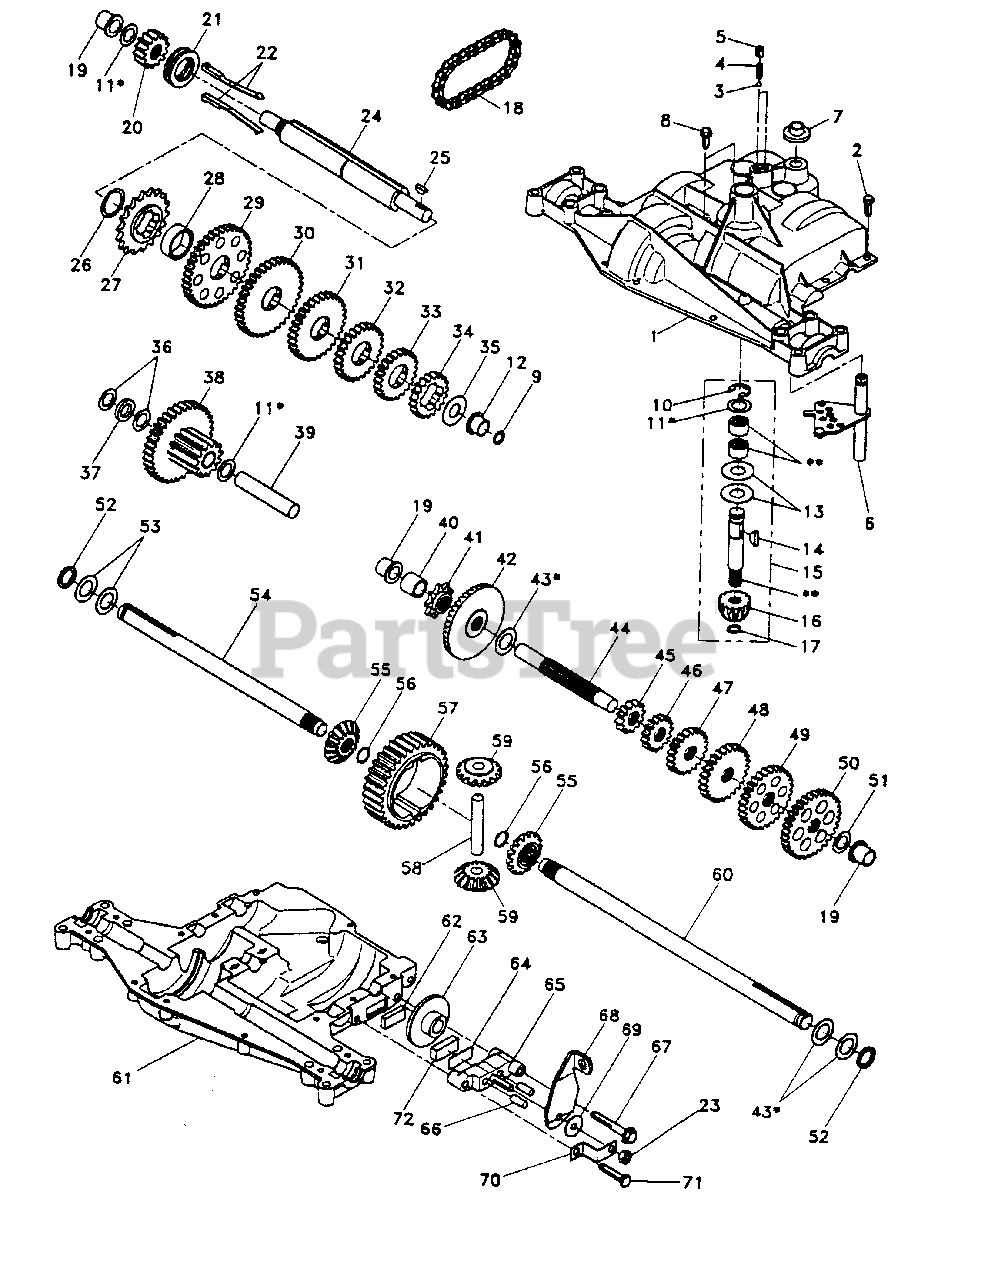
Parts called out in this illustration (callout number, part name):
1	Housing, Upper (AYP part number)
2	Screw, Self-Tapping, Large 1/4-20 x .734 (AYP part number)
3	Ball, Detent (AYP part number)
4	Spring, Detent (AYP part number)
5	Screw, Set (AYP part number)
6	Kit, Shifter Assembly (AYP part number)
7	Boot, Shifter (AYP part number)
8	Screw, Self-Tapping, with Sealer (AYP part number)
9	Square Ring (AYP part number)
10	Ring, Retaining (AYP part number)
11	Assembly, Kit, Shim .625 Shaft (AYP part number)
12	Bearing, Flange (AYP part number)
13	Washer, Plain .632 x 1.38 x .046 (AYP part number)
14	Key, Woodruff, #9 (AYP part number)
15	Assembly, Kit, Input Shaft (AYP part number)
16	Pinion, Bevel, 14 Teeth (AYP part number)
17	Ring, Retaining (AYP part number)
18	Chain, 24 Pitches (AYP part number)
19	Bearing, Flange (AYP part number)
20	Gear, Spur, 14 Teeth (AYP part number)
21	Collar, Clutch (AYP part number)
22	Assembly, Kit, Clutch Keys (AYP part number)
23	Locknut 5/16-24 (AYP part number)
24	Shaft, Intermediate (AYP part number)
25	Key, Woodruff, #61 (AYP part number)
26	Ring, Retaining (AYP part number)
27	Sprocket, 18 Teeth (AYP part number)
28	Spacer (AYP part number)
29	Gear, Spur, 37 Teeth (AYP part number)
30	Gear, Spur, 35 Teeth (AYP part number)
31	Gear, Spur, 30 Teeth (AYP part number)
32	Gear, Spur, 25 Teeth (AYP part number)
33	Gear, Spur, 22 Teeth (AYP part number)
34	Gear, Spur, 19 Teeth (AYP part number)
35	Washer, Plain .640 x 1.37 x .061 (AYP part number)
36	Washer, Plain .632 x 1.00 x .026 (AYP part number)
37	Spacer .630 x 1.00 x .169 (AYP part number)
38	Assembly, Gear, Combination of 12 Teeth and 35 Teeth (AYP part number)
39	Shaft, Idler (AYP part number)
40	Spacer .635 x .875 x .755 (AYP part number)
41	Sprocket, 9 Teeth (AYP part number)
42	Gear, Bevel, 42 Teeth (AYP part number)
43	Assembly, Kit, Shim .750 Shaft (AYP part number)
44	Shaft, Drive (AYP part number)
45	Gear, Spur, 12 Teeth (AYP part number)
46	Gear, Spur, 15 Teeth (AYP part number)
47	Gear, Spur, 20 Teeth (AYP part number)
48	Gear, Spur, 25 Teeth (AYP part number)
49	Gear, Spur, 28 Teeth (AYP part number)
50	Gear, Spur, 31 Teeth (AYP part number)
51	Washer, Plain .632 x 1.00 x .060 (AYP part number)
52	Washer, Neoprene (AYP part number)
53	Washer, Plain .758 x 1.25 x .031 (AYP part number)
54	Axle, L.H. (AYP part number)
55	Gear, Miter, 15 Teeth (AYP part number)
56	Ring, Retaining (AYP part number)
57	Gear, Spur, 32 Teeth (AYP part number)
58	Shaft, Cross (AYP part number)
59	Gear, Miter, 15 Teeth (AYP part number)
60	Axle, R.H. (AYP part number)
61	Housing, Lower (AYP part number)
62	Puck, Friction (AYP part number)
63	Disc, Brake (AYP part number)
64	Spacer (AYP part number)
65	Jaw, Brake (AYP part number)
66	Pin, Dowel (AYP part number)
67	Screw, Self-Tapping, Large 5/16-18 x 2.25 (AYP part number)
68	Lever, Actuating (AYP part number)
69	Washer, Plain .321 x 1.00 x .055 (AYP part number)
70	Bracket, Anti-Rotation (AYP part number)
71	Screw, Self-Tapping, Large 5/16-18 x 1.44 (AYP part number)
72	Puck, Friction (AYP part number)
73	Grease (AYP part number)
